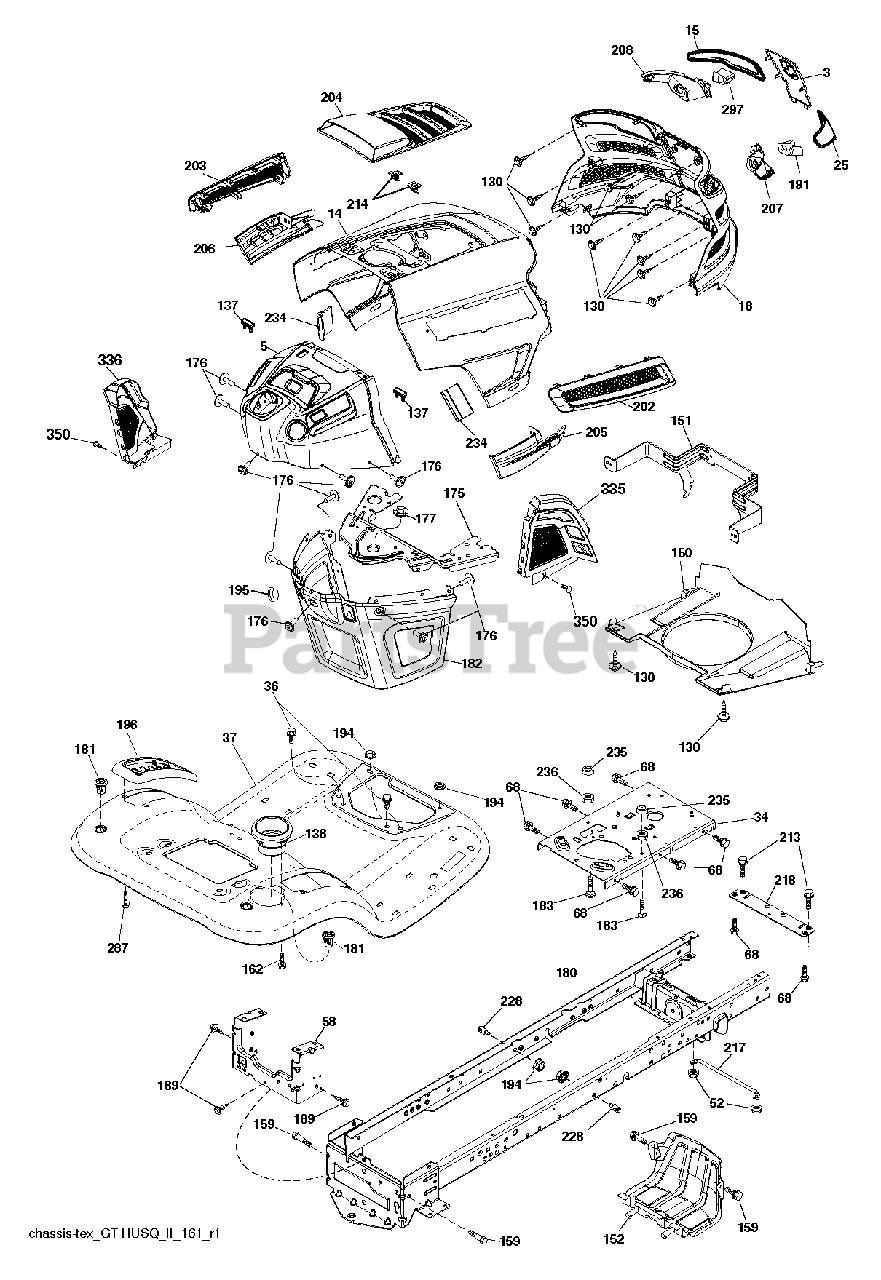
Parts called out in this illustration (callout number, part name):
3	APPLIQUE.SUBASM.GT.HUSQ.II
5	UPPER.GT2.SVC.MINDING.C-O.M;H
14	HOOD.ASM.HUSQVARNA.GT.TEX.422
15	LENS.HEADLIGHT.LH.GTII.2011
18	GRILLE.SUBSTRATE.2011.
25	LENS.HEADLIGHT.RH.GTII.2011
34	PLATE.ENGINE.WELDED.CHASSIS
36	SCREW 5/16"
37	FENDER.TLT.PDL.CNTRL.W/CPH.ORG
52	LOCKNUT
58	DRAWBAR UPPER 2PC SMALL FENDER
68	SCREW LT
130	SCREW.#10 X 0.750.BOS
137	BUMPER DASH
138	HOLDER.CUP.LT.GREY
150	AIR.DUCT.GTV2(2.54"RING HEIGHT
151	BRACKET.PIVOT.HOOD.GT.HUSQ.II
152	SHIELD.BROWNING.PNT.GT.V2
159	SCREW, 3/8-16X3/4
162	SCREW.HI-LO.CONSOLE
175	PLATE.CROSSMEMBER.HUSQ
176	SCREW.#10-24X5/8.RN.QU
177	BUSHING STEERING
180	CHASS.WLDMNT.TL.12GA/2P.48/54
181	BUSHING.MNT.FEND.CRGO.TEX.49
182	DASH LOWER.HUSQ.PRED NO CRUISE
183	BOLT.5/16-18X1-1/4 FULL THD
189	SCREW
191	INSERT.REFLECTIVE.RH.HUSQ.GTII
194	NUT LOCK HEX FLANGE 5/16-18
195	DECKLFT.CONSOL FULL ASSM GREY
196	CONSOLE.ASM.DCKLFT.RBT.TLT.498
202	VENT.SIDE.RH.GT.HUSQ.II.
203	VENT.SIDE.LH.GT.HUSQ.II.498
204	VENT.TOP.HUSQ.GT2
205	SIDE.TRIM.RH.GT.HUSQ.II
206	SIDE.TRIM.LH.GT.HUSQ.II.GRAY
207	BEZEL LIGHT.RH.GT.II.MYLAR
208	BEZEL LIGHT.LH.GT.II.MYLAR
213	BOLT
214	CLIP.RETAINER.TINNER.
217	ROD.PIVOT.HOOD
218	X-PIECE.HOOD.STOP.NON/
228	STUD.FASTNER.W/ANTI-ROTATE
234	BUMPER.HOOD.TEX.HUSQVARNA
235	SPACER FENDER
236	NUT.CENTERLOCK.5/16-
287	SCREW 1/4X20
297	INSERT.REFLECTIVE.LH.HUSQ.GTII
335	COVER.RH.CLOSE.OUT.BLACK
336	COVER-LH.LOWER.DASH.GT2.BLACK
350	CLIP.X-MAS.TREE
